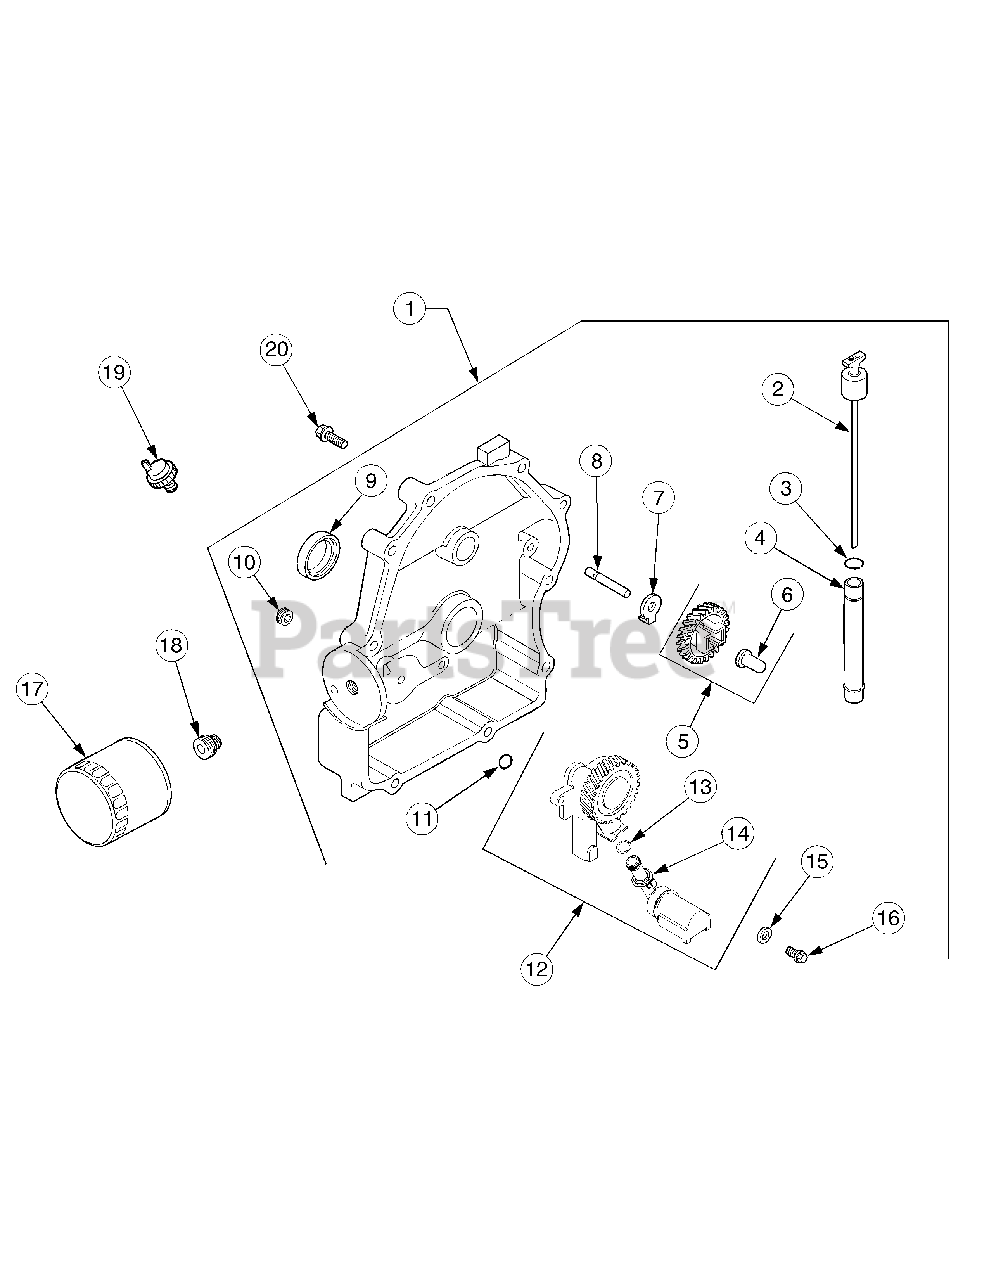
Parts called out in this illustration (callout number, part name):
1	Plate Assy, Closure (Incl. Ref #2-15)
4	Tube, Oil Fill/Dipstick
5	Kit, Governor Gear (Incl. Ref #6)
6	Pin, Governor Regulating
8	Shaft, Governor Gear
9	Seal, Oil (PTO end)
10	Plug, Pipe 1/8
12	Oil Pump Assy (Incl. Ref #13-14)
13	O-Ring, Oil Pick-up
14	Pick-up, Oil
15	Washer, Plain
16	Screw, Hex Flange, M6 x 1.0 x 25
18	Nipple, Oil Filter
19	Switch, Pressure
20	Screw, Hex Flange, M8 x 1.25 x 45
